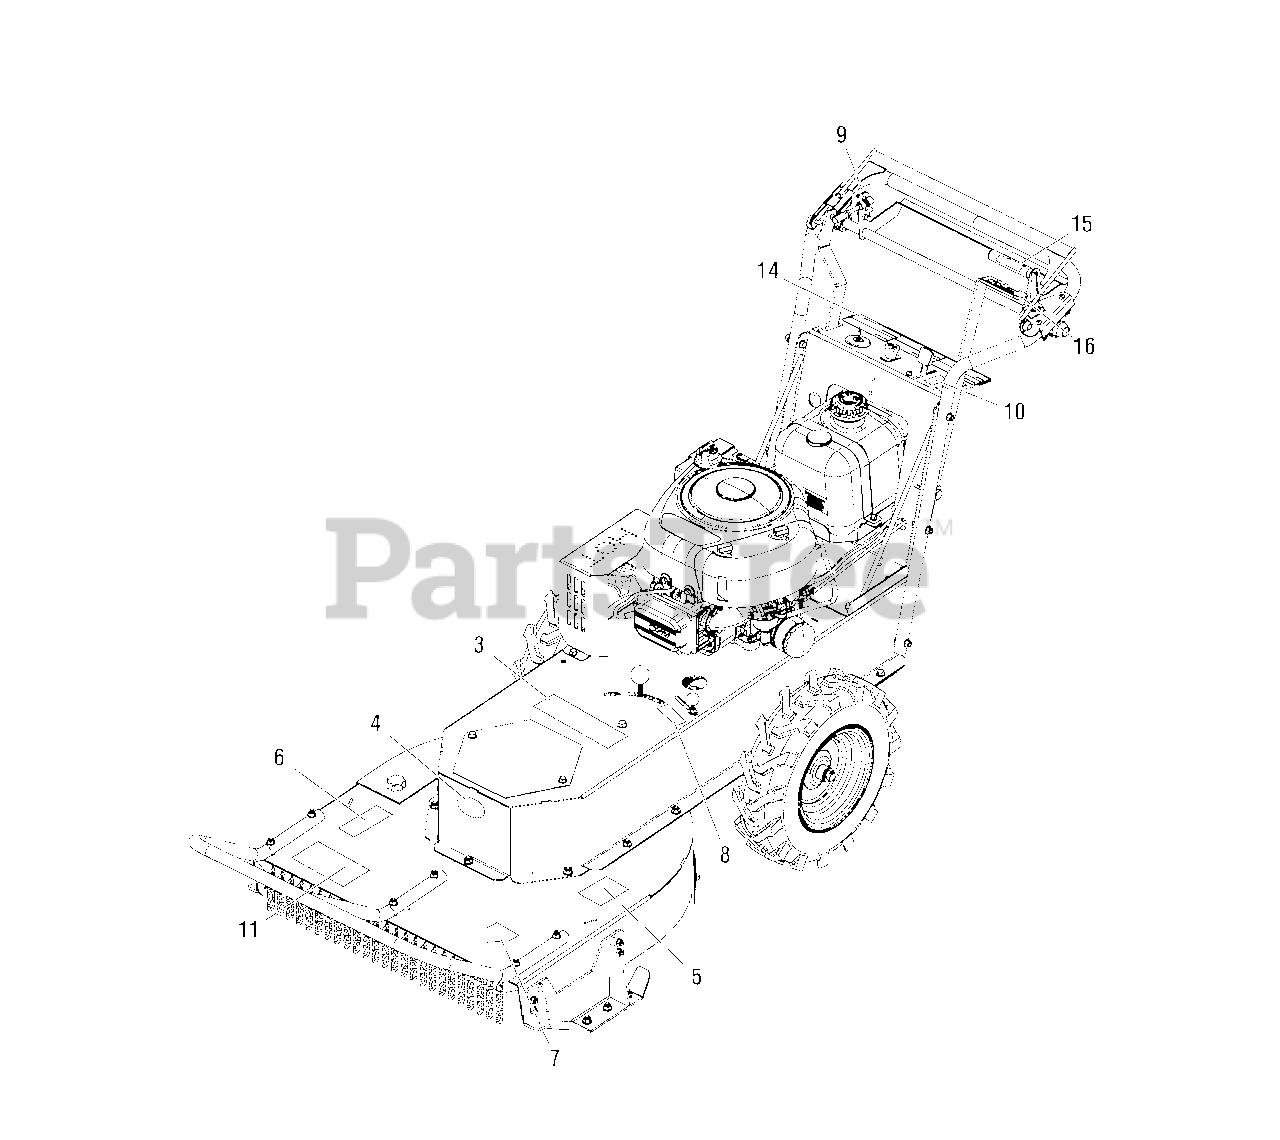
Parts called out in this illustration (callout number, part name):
3	DECAL, Snapper Logo
4	DECAL, Snapper Turtle
5	DECAL, Warning Serious Injury
6	DECAL, Danger Amputation and Thrown Objects
7	DECAL, Danger, Hands & Feet
8	DECAL, Free Wheel / Drive
9	DECAL, Speed Control
10	DECAL, Throttle, - Chock-Rabbit-Turtle
11	DECAL, Warning Avoid Serious Injury Instructions
12	Serialization Tag
13	CARB / EVAP Compliance
14	DECAL, Quick Start
15	DECAL, Grip, Reverse Lever
16	DECAL, Grip, Parking Brake
